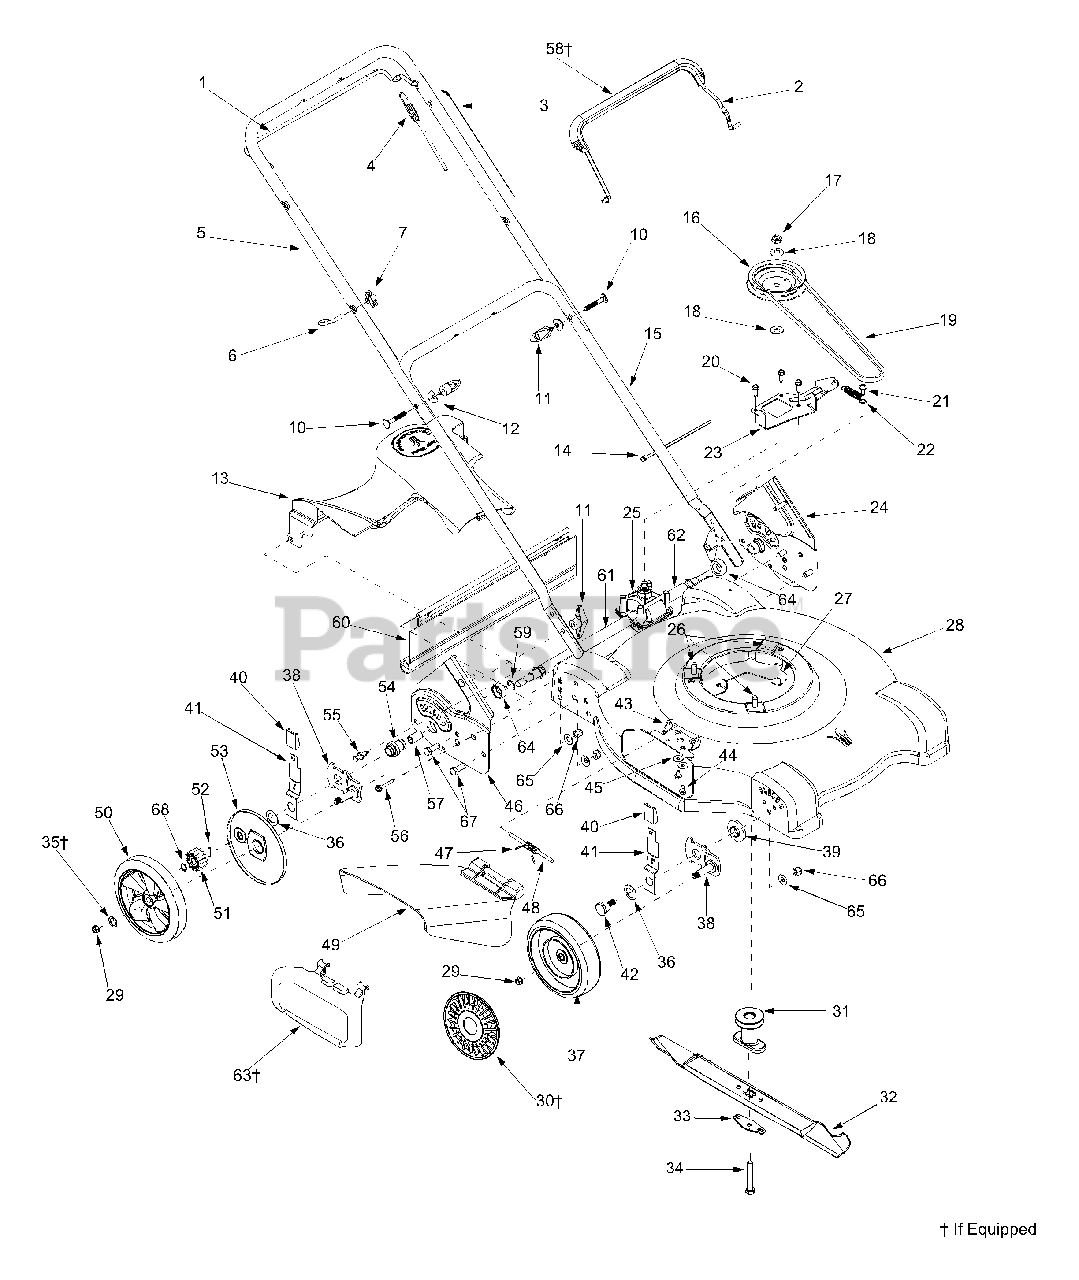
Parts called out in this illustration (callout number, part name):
1	Drive Control Handle
3	Blade Control Cable - 37.75"
4	Drive Control Cable
6	Eye Bolt
7	Wing Nut 1/4-20
10	Carriage Bolt 5/16-18 x 2.0
11	Wing Nut 5/16-18
12	Shoulder Washer.320 ID x.93 OD
13	Transmission Cover
14	Cable Tie
16	Transmission Pulley
17	Jam Nut 7/16-20
18	Bell Washer.45 ID x 1.00 OD
19	V-Belt
20	Hex Washer Screw 1/4-20 x.75
21	Shoulder Screw.375 x.25
22	Extension Spring
23	Transmission Belt Bracket
26	Hex Washer Screw 3/8-16 x 1.0
27	Engine Belt Keeper Bracket
30	Hub Cap If equipped
31	One Piece Blade Adapter
32	22" Mulching Blade
33	Bell Blade Support
34	Hex Cap Screw 3/8-24 x 2.5
35	Flat Washer 1/2 x 1.00 x.030 If equipped
36	Bell Washer.401 ID x.870 OD
37	Front Wheel 7 x 2 Link Black BB
38	Pivot Arm Assembly
39	Height Adjuster Bearing
40	Height Knob
41	Spring Lever
42	Shoulder Screw 3/8-16
43	Deflector Chute Adapter
44	Hex Washer Screw 1/4-20 x.50
45	Bell Washer.265 ID x.75 OD
48	Hinge Pin
49	Side Discharge Chute Assembly
50	Rear Wheel 8 x 2 Link Black
51	Spur Gear 14T RH
52	Pin
53	Wheel Cover
54	Bearing Support
55	Plastic Rivet
56	Screw 1/4-20
57	Sleeve Bearing
58	Deluxe Bail Cover If equipped
59	Retainer Ring
60	Trail Shield
61	Sleeve Spacer.550 ID x 9.0 OD
62	Sleeve Spacer.550 ID x 2.44 OD
63	Snap Mulching Plug If equipped
64	Bearing Spacer
65	Bell Washer.401 ID x.870 OD
66	Hex Lock Nut 3/8-16
67	Hex Cap Screw 3/8-16 x 1.0
68	Snap Ring.500
